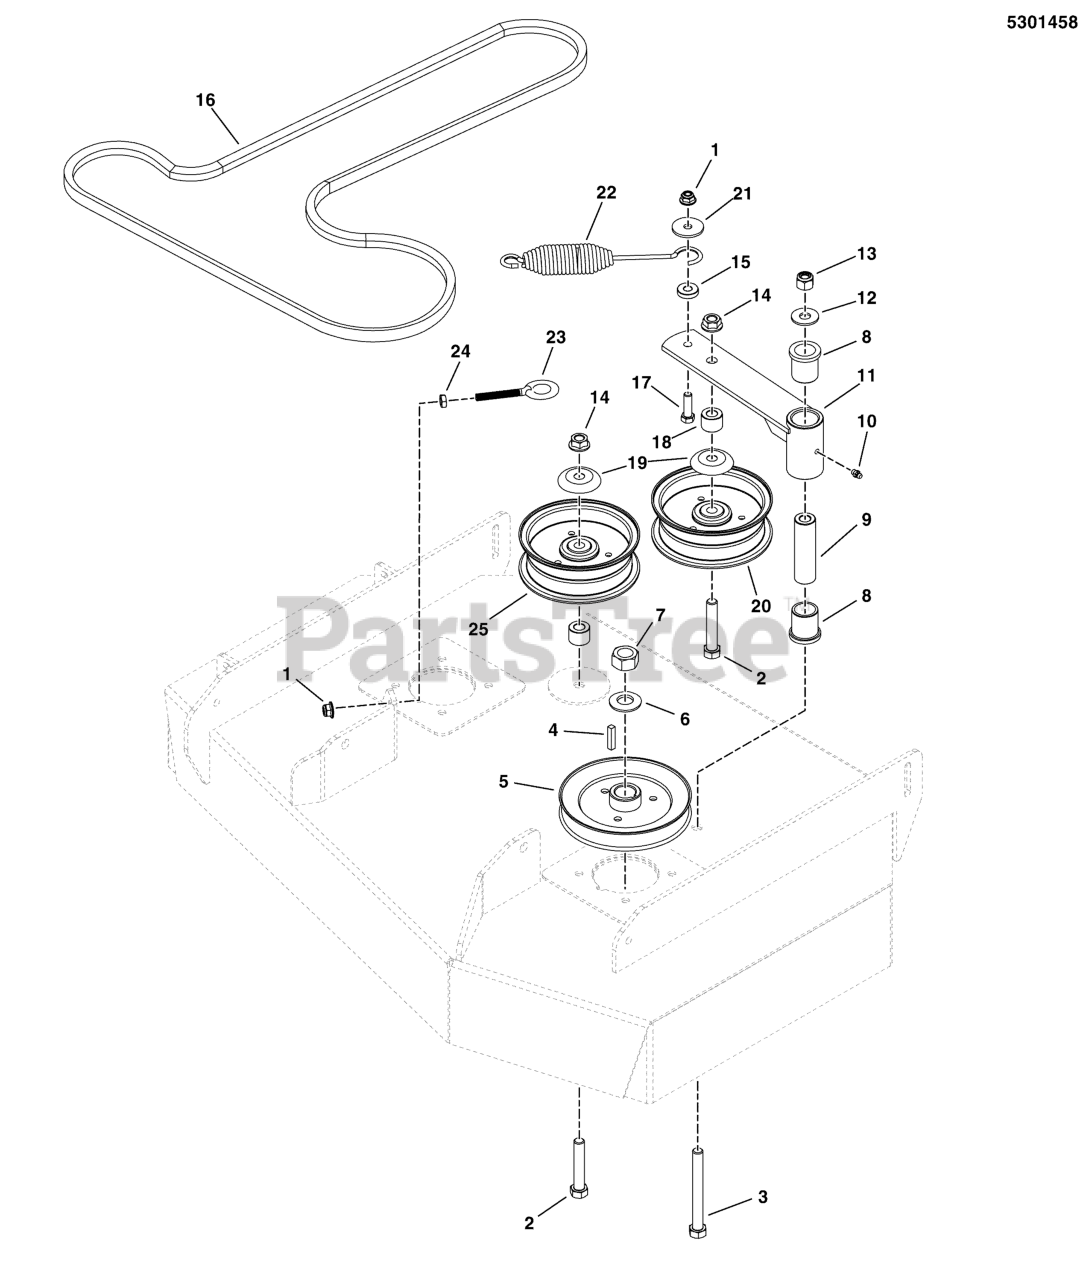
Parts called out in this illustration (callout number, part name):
1	NUT, 3/8-16 HEX NYLOCK FLANGE
2	BOLT, 1/2-13 X 2-3/4 GD5 CZ
3	BOLT, 1/2-13 X 4-1/2 GD5
4	KEY, 1/4 SQ. X 1-1/4
5	PULLEY-6.122 OD. X .98 BORE
6	WASHER, 3/4 BELLEVILLE
7	NUT, 3/4-16 HEX
8	BUSHING, FLANGE
9	SPACER, .52 X 1.00 X 3.50
10	GREASE FITTING, 1/4-28 STRAIGHT
11	WELD, IDLER ARM, SHORT - BLK
12	WASHER, 1/2 USS
13	NUT, 1/2-13 HEX NYLON LOCK
14	NUT, Hex Flange, Nylock, 1/2-13
15	SPACER, .39 X 1.00 X .25
16	BELT, #7-5335
17	BOLT, 3/8-16 X 1-1/4" GD5 CZ
18	SPACER, .52 X 1.00 X .75
19	SHIELD, PULLEY BEARING
20	PULLEY, IDLER, 5.00 WIDE W/ .51 BORE
21	WASHER, .390 X 1.50 X .109, YZ
22	SPRING, EXTENSION, SWIVEL. LONG HOOK
23	EYE BOLT, 3/8-16 X 5, 2.88THRD, 1EYE, CZ
24	NUT, 3/8-16 HEX JAM
25	PULLEY, IDLER, 5" OD, 1"FACE, 5.75 FL
